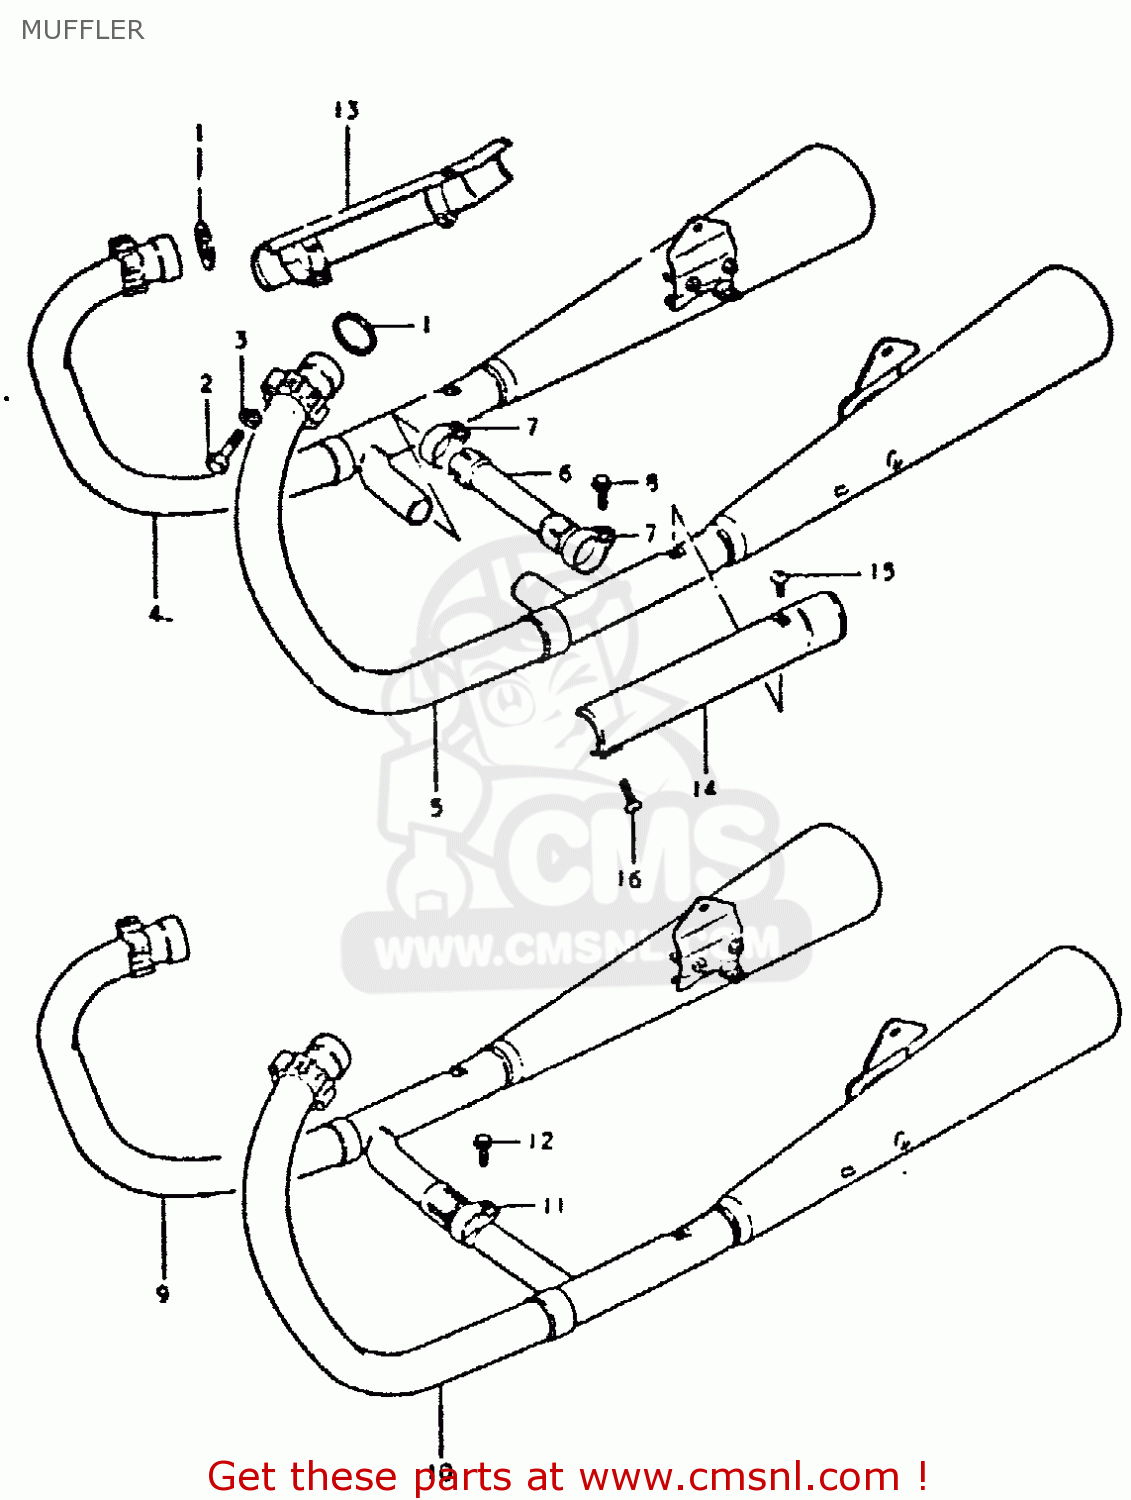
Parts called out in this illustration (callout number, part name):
1	GASKET,EXHAUST PIPE (NAS)
2	BOLT
3	LOCK WASHER
4	MUFFLER, RH
5	MUFFLER, LH
6	PIPE,EXHAUST COUPLER
7	CLAMP
8	BOLT
9	MUFFLER, RH
10	MUFFLER, LH
11	CLAMP
12	BOLT
13	COVER,MUFFLER
14	COVER,MUFFLER
15	SCREW
16	SCREW
